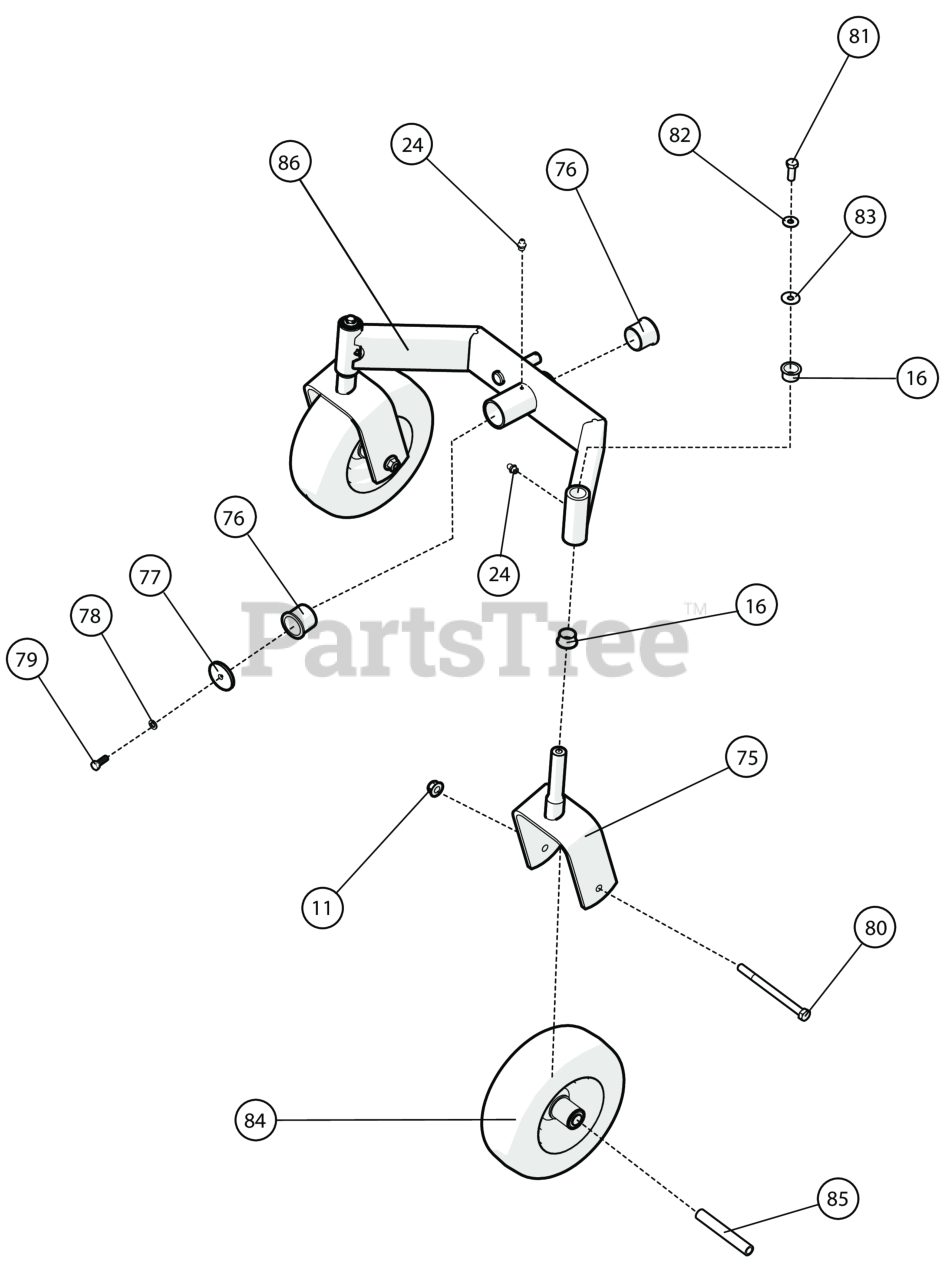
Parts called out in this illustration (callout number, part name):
11	NUT-HEX-NYLK, FLG .500"-13 ZP
16	BUSHING, 1.00" ID
24	ZERK FITTING GREASE
75	WA, CASTER FORK
76	BUSHING 1.500 ID X 1.5 LONG FLANGED
77	WASHER DECK RETAINING
78	WASHER LOCK 3/8" S/T MED
79	SCREWCAP 3/8"-24 X 1" HCS GR 8
80	SCREWCAP 1/2-13 X 6 1/2" HCS ZP
81	SCREWCAP 3/8"-16 X 1" HCS ZP
82	WSHR-STL, BLV, .386" X 1.063" X .082" MZ
83	WSHR-STL, FLT .410"X1.250"X.065" FEN ZP
84	ASM, WHEEL & TIRE, 11X4.00-5, FLAT FREE
85	CASTER AXLE, .75 x 5.075
86	WA, CASTER RIG
